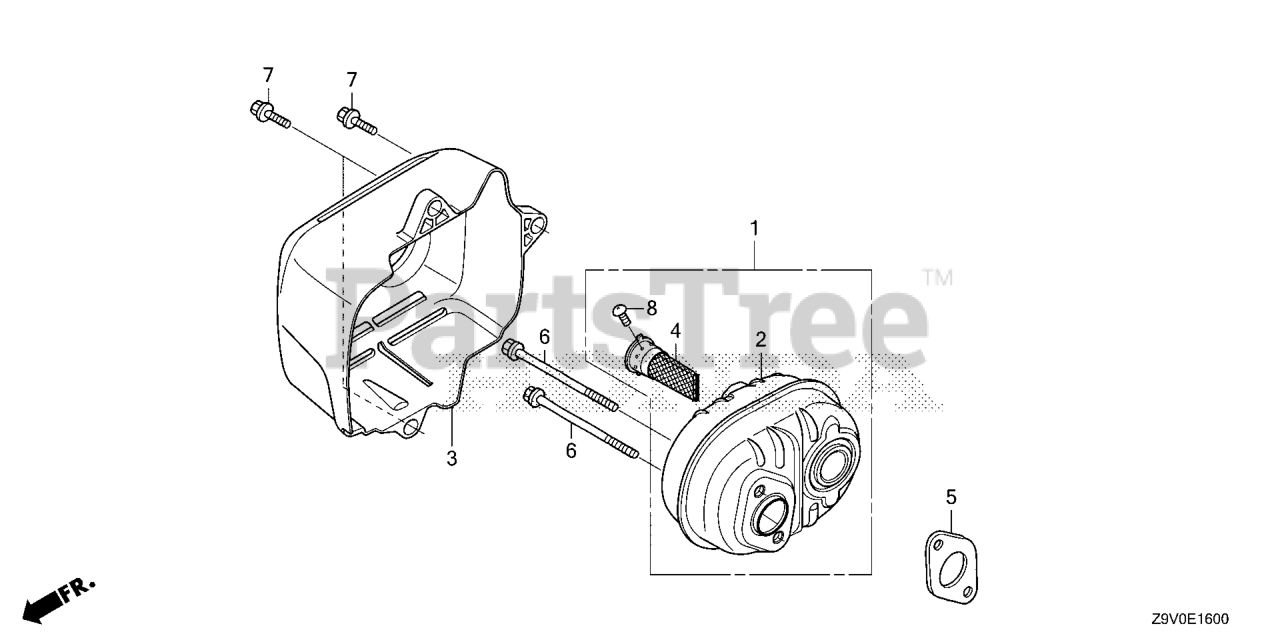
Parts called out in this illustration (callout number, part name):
1	MUFFLER ASSY. (ARRESTER)
3	PROTECTOR, MUFFLER
4	ARRESTER, SPARK
5	GASKET, MUFFLER
6	BOLT, FLANGE (6X79) (CT200)
7	BOLT, FLANGE (6X23)
8	SCREW, TAPPING (4X6) (TO INSTALL OPTIONAL SPARK ARRESTER)
